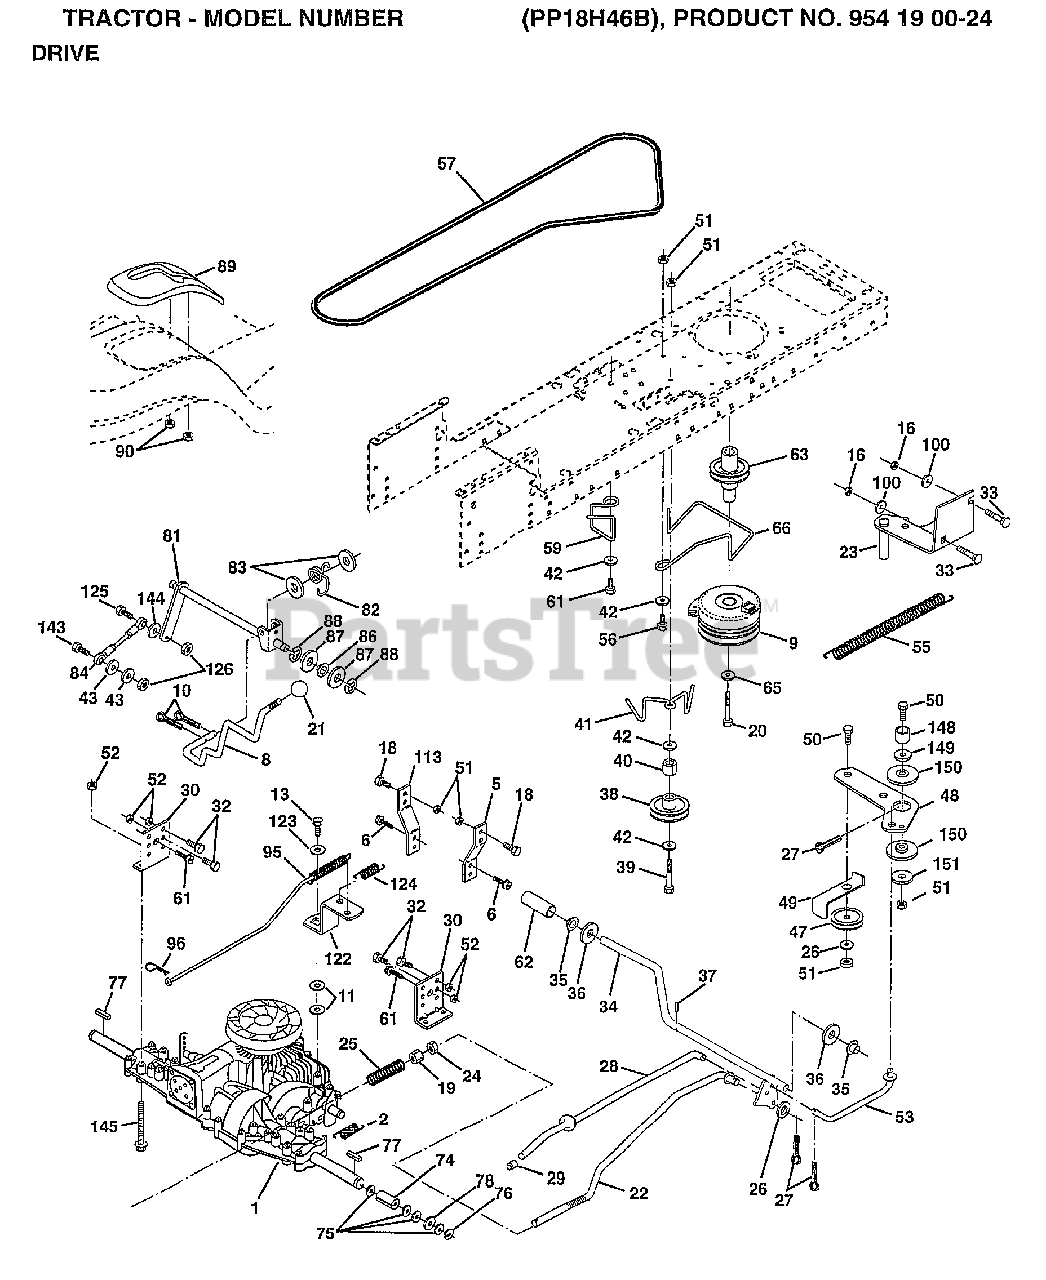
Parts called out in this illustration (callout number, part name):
2	SPRING.BRAKE.RETU
5	STRAP TORQUE
6	SCREW
8	"ROD SHIFT,FENDER"
9	CLUTCH.ELECTRIC
10	PIN COTTER 1/8
11	WASH-SHFT PLT LT
13	BOLT.1/4-28.W/PAT
16	NUT
18	BOLT
19	NUT
20	BOLT.7/16-20X4.25
21	KNOB.DUCKHEAD.1/2
22	BRAKE ROD
23	BRACKET.CLUT.MTG.
24	NUT
25	SPRING ROD LT
26	WASHER
27	COTTER PIN
28	ROD.BRAKE.PARK.LT
29	PLUNGER CAP T
30	TRANSAXLE MTG BKT
32	BOLT
33	BOLT
34	SHAFT ASM-PEDAL F
35	NYLON BEARING
36	WASHER LT
38	PULLEY.IDLER.FLAT
39	BOLT
40	SPACER T
42	WASHER
43	WASHER T
48	BELLCRANK.CLUTCH
49	RETAIN BELT
53	"LINK, CLUTCH T"
55	"SPRING, RETURN LT"
57	"V-BELT,GROUND DRV"
59	KEEPER BELT CNTSP
61	SCREW
62	PEDAL COVER T
63	PULLEY.ENGINE
65	LOCKWASHER
66	ENGINE BELT KEEPR
74	"SPACER AXLE,PVST"
75	WASHER
76	E-RING LT
77	SQUARE KEY
78	WASHER
81	SHAFT ASM CROSS
82	"SPRING,TORSION"
83	WASHER
84	"ROD TIE, PVST 20"""
86	BUSHING
87	WASHER D
88	KLIP RING
90	NUT
95	ROAD ASM BYPASS
96	RETAINER M
100	WASHER M
113	"STRAP,TORQUE"
122	"PLATE-BYPASS,PVST"
123	WASHER
124	SPRING RETURN
143	BOLT
144	WASHER
145	BOLT.HEX.FLGHD
149	SPACER RETAINER
150	BUSHING.NYLON
151	WASHER
